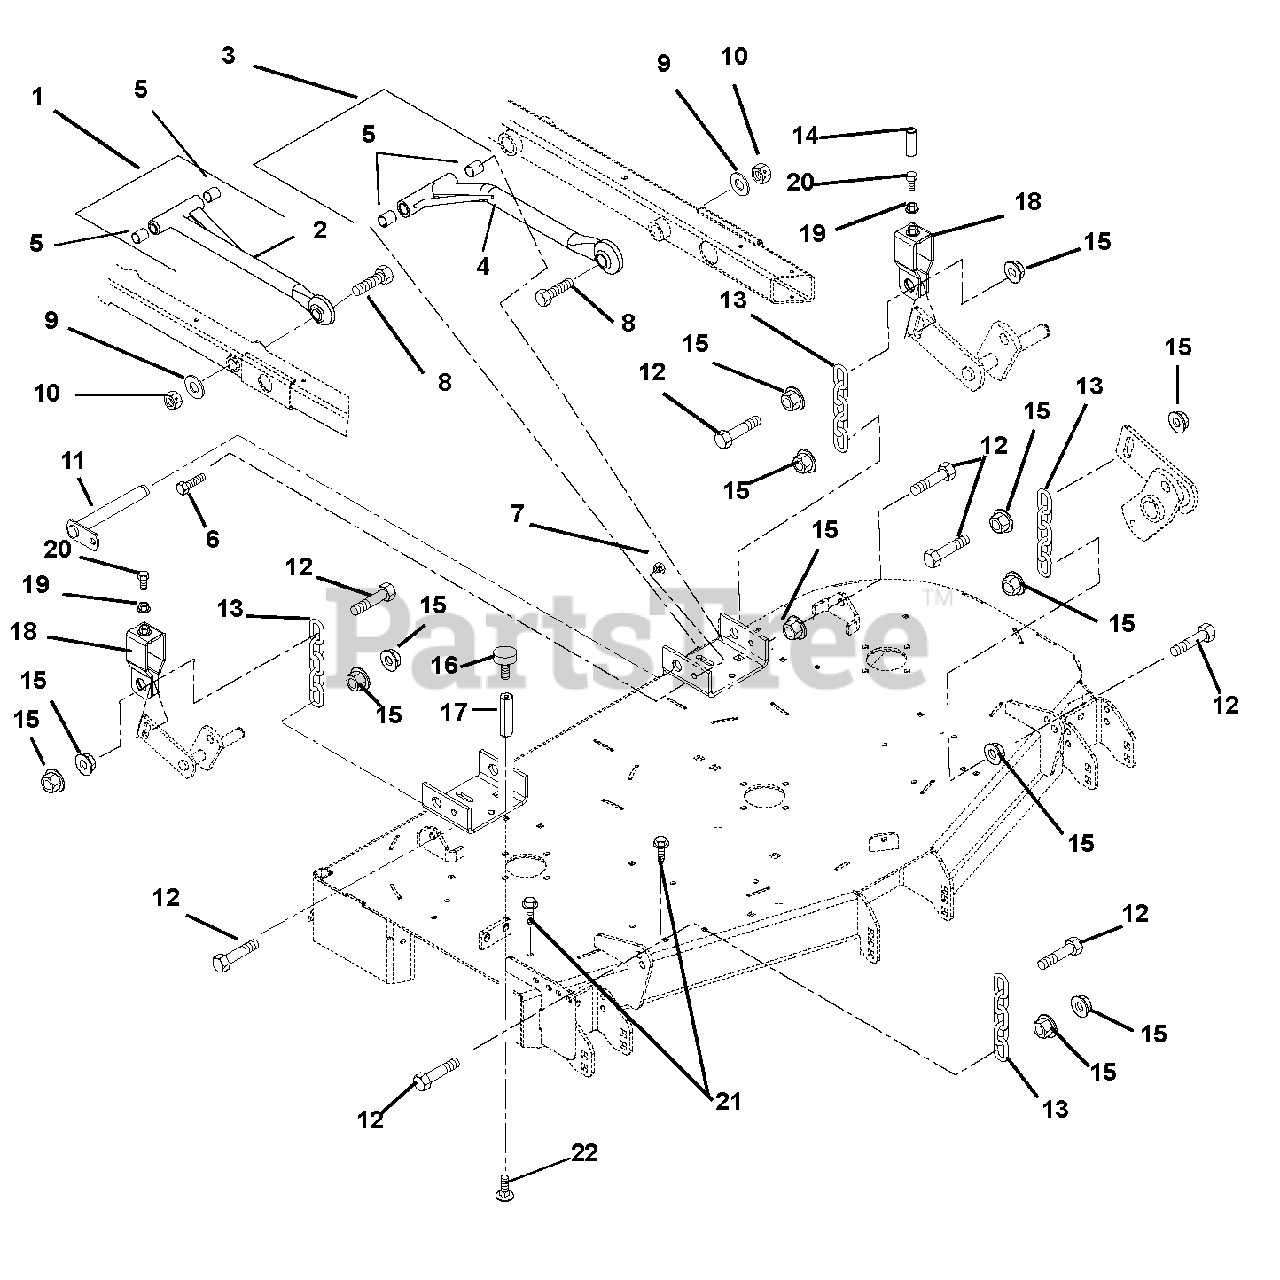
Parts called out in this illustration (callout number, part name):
1	Assembly, Mower Mounting Arm (Contains Items 2, 5)
2	Weldment-Mower Mounting Arm
3	Assembly, Mower Mounting Arm Left Hand (Contains Items 4,5)
4	Weldment, Mower Mount Arm
5	Bearing .75 x .875 x 1.00
6	Bolt-Hex .38-16 x .75 Grade 5
7	Nut, .38-16 Nyloc Flange
8	Bolt,Hex .875 x 5.50 Grade 5
9	Washer-Flat-Steel .875 x 1.500 x .1196
10	Nut-Locking-Center .875-9
11	Weldment, Mower Mounting Pin
12	Bolt, Hex M12-1.75 x 50 Grade 5
13	Chain, Link
14	Cap, Vinyl .50 ID x 1.50LG x .055
15	Nut, Spin Lock-Flange M12-1.75
16	Bumper, Rubber
17	Nut, Coupling .31-18 x 2.00
18	Bracket, Deck Leveling
19	Nut, Jam .312-18
20	Bolt, Full Thread Hex .312-18 x 2.00
21	Screw, Tapping Hex Washer Head Thread .38-16 x .50
22	Bolt, Round Head Square Neck .31-18 x .75
